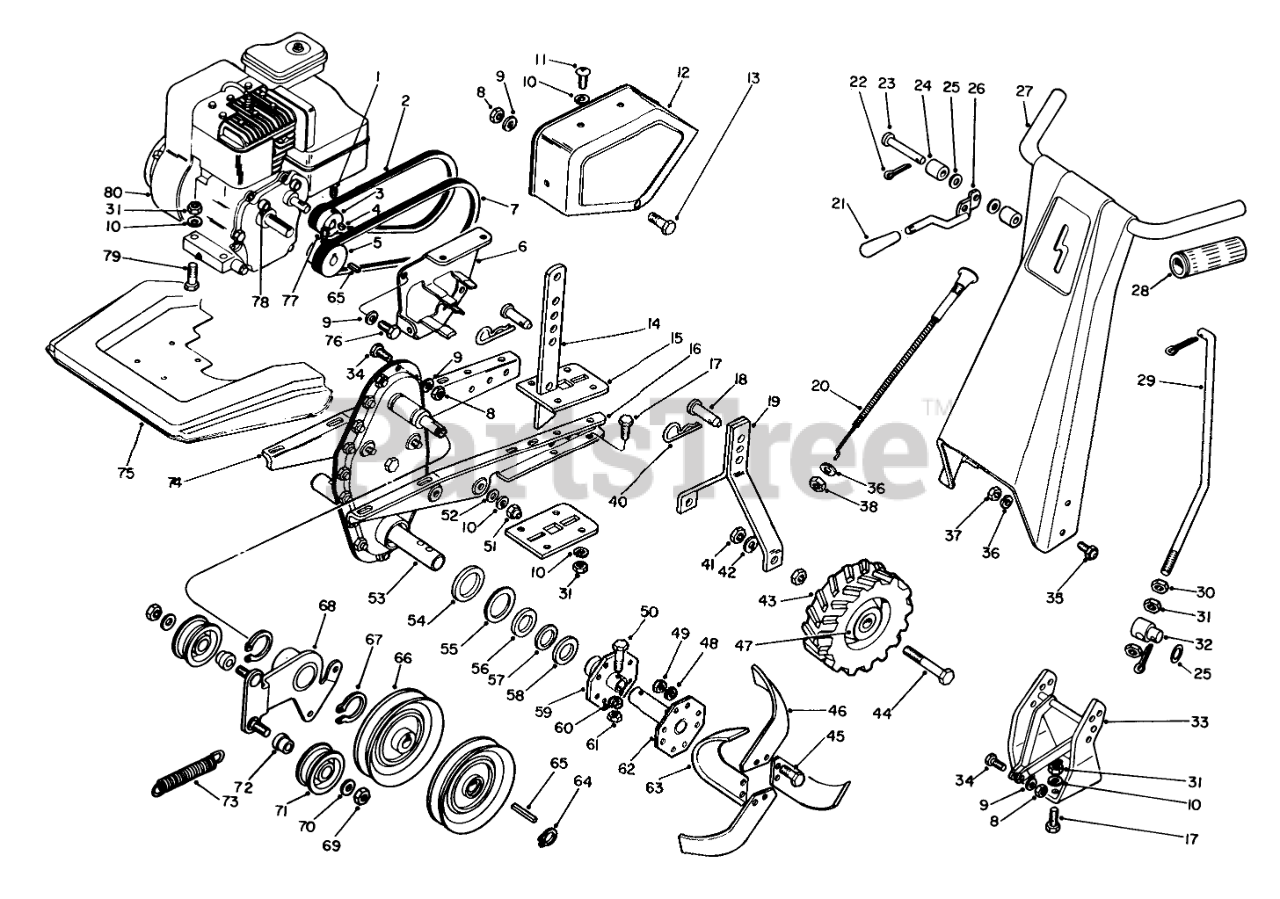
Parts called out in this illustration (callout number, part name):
1	SCREW-SET
2	Nut
3	Camshaft Pulley
4	KEY-WOODRUFF
5	Pulley-Engine
6	Bracket
7	V-Belt-Forward
8	NUT-HEX
9	WASHER-LOCK
10	WASHER-LOCK
11	Pan Hd. Mach. Screw
12	Belt Guard w/Decal
13	SCREW-HH
14	Depth Control
15	Plate-Hitch
16	Frame-L.H.
17	SCREW-HH
18	Clevis Pin
19	Wheel Hanger
20	Throttle Control
21	Knob
22	PIN-COTTER
23	Clevis Pin
24	Rubber Disc
25	WASHER-PLAIN
26	Clutch Lever
27	Handle w/Decal
28	Grip
29	Control Rod
30	NUT-JAM
31	NUT-HEX
32	Swivel
33	Handle Support
34	SCREW-HH
35	Acorn Hd. Bolt
36	WASHER-LOCK
37	NUT-HEX
38	NUT-HEX
40	Spring Clip
41	NUT-JAM
42	WASHER-LOCK
43	Tire & Wheel Assembly L.H.
44	SCREW-HH
45	Tine Bolt
46	Tine R.H.
47	Tire & Wheel Assembly R.H.
48	WASHER-LOCK
49	NUT-HEX
50	Capscrew
51	NUT-LOCK, CONE
52	WASHER-PLAIN
53	Chain Case Assembly
54	Washer
55	Felt Seal
56	Felt Seal
57	Washer
58	Felt Seal
59	Inner Tine Hub
60	WASHER-LOCK
61	NUT-HEX
62	Outer Tine Hub
63	Tine L.H.
64	Retaining Ring
65	SQUARE KEY
66	Pulley
67	RING-RETAINING
68	Idler Arm
69	NUT-LOCK, CONE
70	WASHER-FLAT
71	Idler Pulley
72	Spacer
73	Spring
74	Frame R.H.
75	Tine Shield
76	SCREW-HH
77	SCREW-SET, HSH
78	Spacer
79	SCREW-HH
80	Engine
